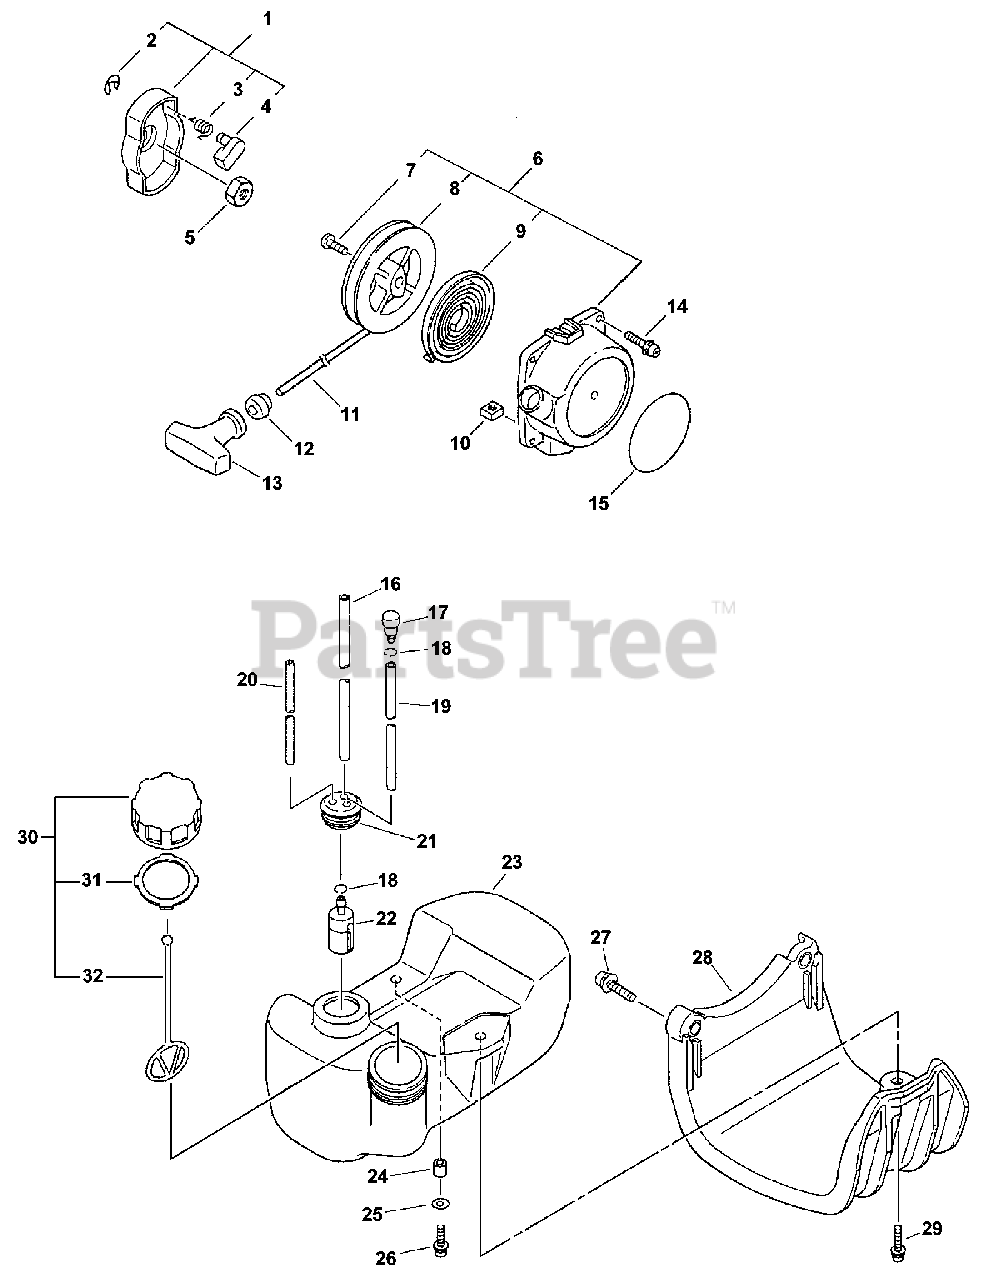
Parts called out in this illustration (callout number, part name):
1	STARTER PAWL ASSY
2	RING, RETAINING - 4
3	SPRING, RETURN
4	PAWL, STARTER
6	STARTER ASSY
8	REEL, ROPE
9	SPRING, REWIND
10	NUT - 5 -- SQUARE
11	ROPE, STARTER - 3.5X850
12	GUIDE, ROPE
13	GRIP, STARTER
14	SCREW - 4X12
15	LABEL - ECHO
16	PIPE, FUEL - SPIRAL
17	VENT, FUEL TANK
18	CLIP - 6.5
19	PIPE - 3X6X115 -- BLACK
20	PIPE - 3X6X80 -- CLEAR
21	GROMMET
22	FILTER, FUEL
23	FUEL TANK ASSY
25	WASHER - 5
26	SCREW - 5X16
27	SCREW - 5X22
28	GUARD, FUEL TANK
29	SCREW - 5X20
30	CAP ASSY - ORANGE
31	GASKET, CAP
32	CONNECTOR, CAP
